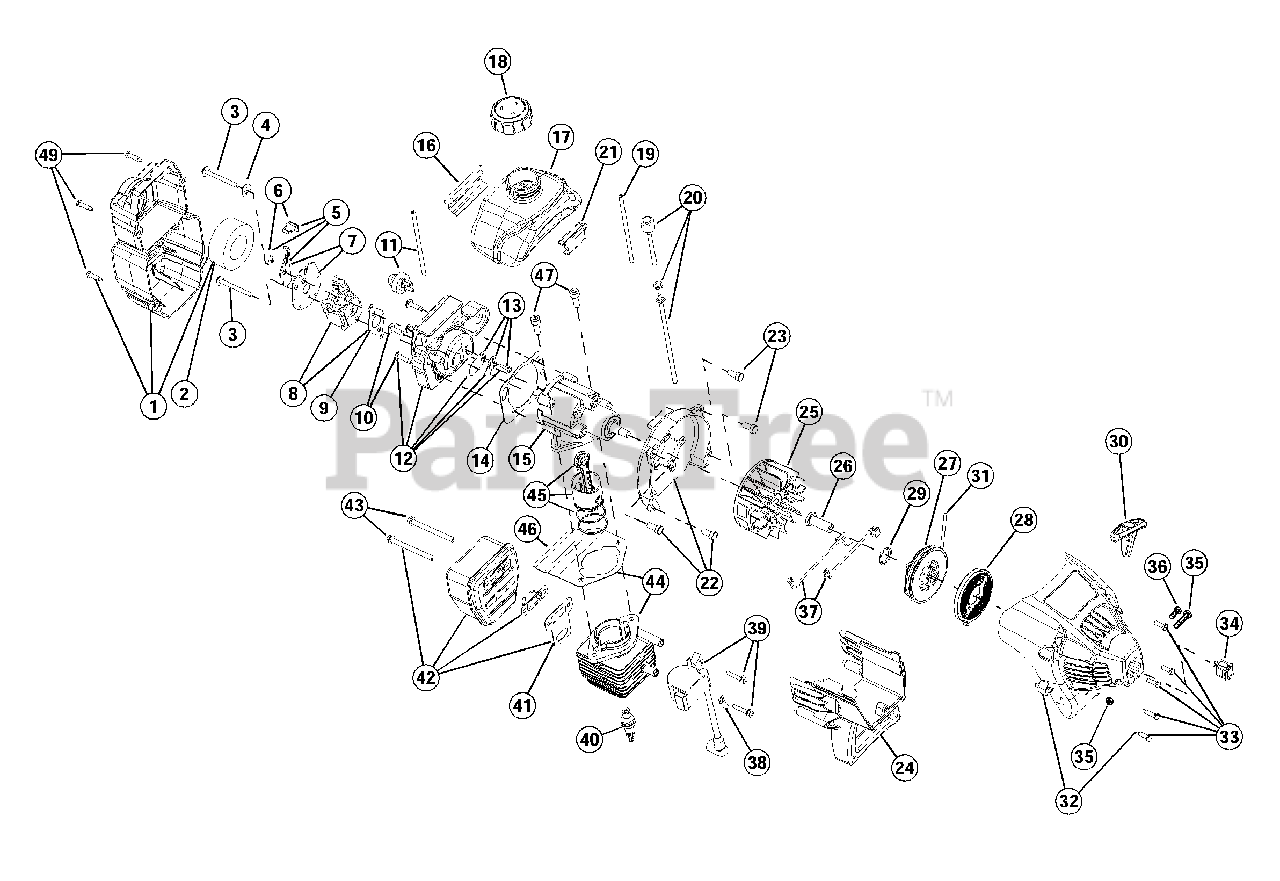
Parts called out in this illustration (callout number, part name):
1	Air Cleaner/Muffler Cover Assembly
2	Air Cleaner Filter
3	Carburetor Mounting Screws
4	Wavey Washer
5	Choke Lever Assembly
6	Choke Knob and Screw
7	Choke Lever and Plate
8	Carburetor Assembly
9	Carburetor Gasket
10	Carb Mount Screw
11	Primer and Hose Assembly
12	Carb Mount Assembly
13	Reed Assembly
14	Carburetor Mount Gasket
15	Crank Case Service Assembly
16	Rear Mounting Pad
17	Fuel Tank Assembly
18	Fuel Cap Assembly
19	Fuel Return Line
20	Fuel Line Assembly
21	Front Mounting Pad
22	Shroud Assembly
23	Shroud Screw
24	Shroud Extension and Stand
25	Flywheel Assembly
27	Recoil Pulley
28	Recoil Spring
29	Pulley Retainer
30	Pull Handle
32	Starter Housing Assembly
33	Housing Screws
34	On/Off Switch
35	Clamping Screw & Nut
36	Anti-Rotation Screw
37	Wire Leads
38	Ground Tab
39	Module Assembly
40	Spark Plug
41	Exhaust Gasket
42	Muffler Assembly
43	Muffler Mounting Bolt
44	Cylinder Assembly
45	Piston and Rod Assembly w/Rings
46	Cylinder Gasket
47	Cylinder Bolt
48	Spark Arrestor Screen
49	Cover Screws
